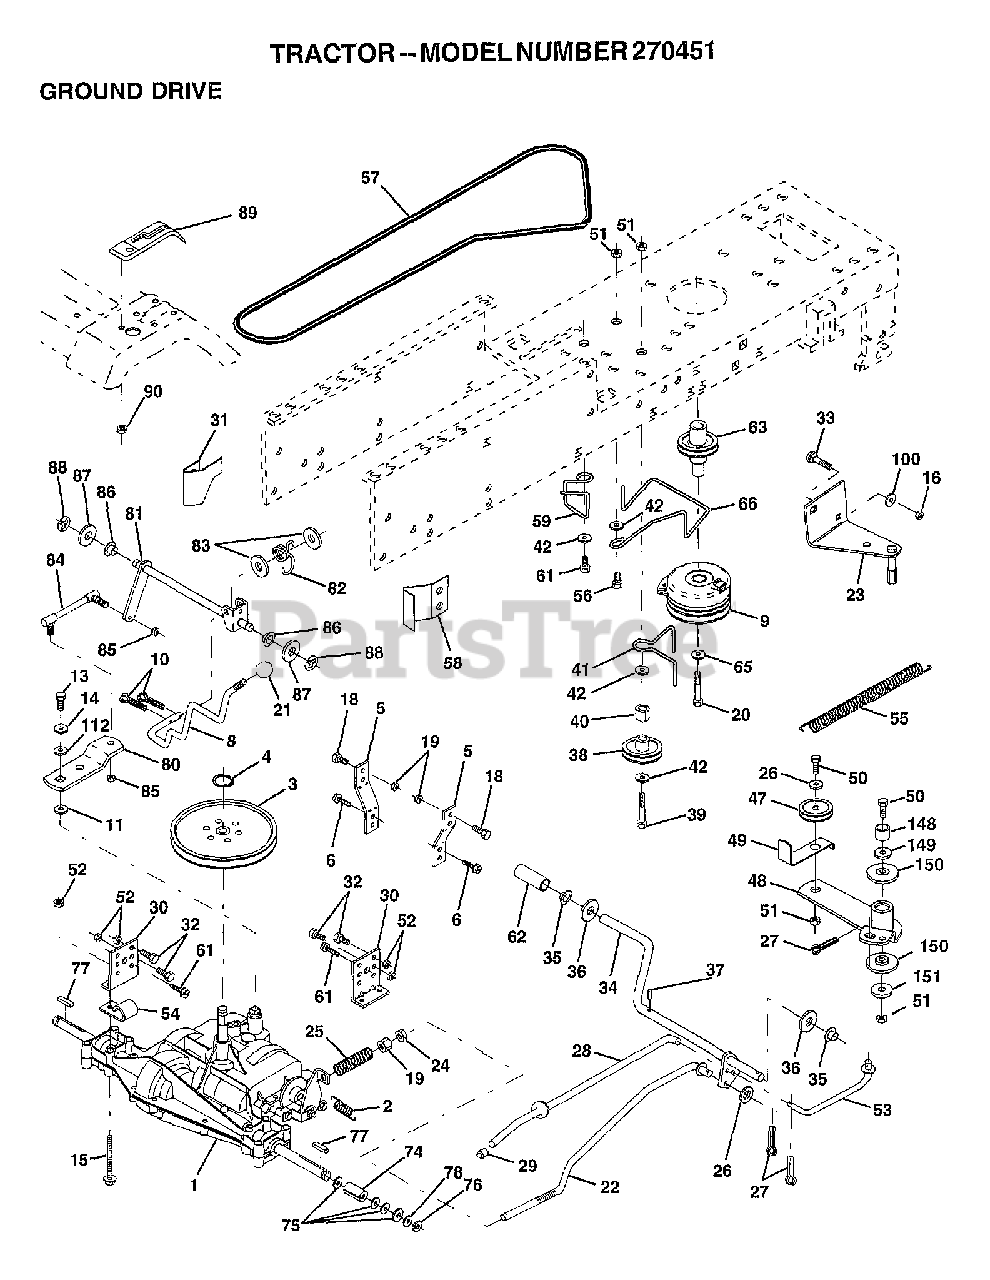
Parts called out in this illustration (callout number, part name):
2	SPRING.BRAKE.RETU
3	PULLEY TRANS
5	STRAP TORQUE
6	SCREW
7	BRKT.SADDLE.SHIFT
8	SHIFT ROD
10	PIN COTTER 1/8
11	WASH-SHFT PLT LT
12	WASHER
13	BOLT.1/4-28.W/PAT
14	LOCKWASHER
15	BOLT.HX.FLG.5/16
18	BOLT
19	NUT
21	KNOB T (1/2-HOLE)
22	BRAKE ROD
24	NUT
25	SPRING ROD LT
26	WASHER
27	COTTER PIN
28	ROD.BRAKE.PARK.LT
29	PLUNGER CAP T
30	TRANSAXLE MTG BKT
32	BOLT
34	SHAFT ASM-PEDAL F
35	NYLON BEARING
36	WASHER LT
38	FLAT IDLER PULLEY
39	BOLT
40	SPACER T
41	"KEEPER,BELT.IDLER FLAT"
42	WASHER
48	BELLCRANK.CLUTCH
49	RETAIN BELT
53	"LINK, CLUTCH T"
55	"SPRING, RETURN LT"
57	"V-BELT,95.3"
59	KEEPER BELT SPAN CTR
61	SCREW
62	PEDAL COVER T
63	PULLEY.ENGINE
64	BOLT
65	LOCKWASHER
66	KEEPER-BELT
70	KEEPER BELT ENG
72	WASHER
74	SPACER LT
75	WASHER
76	E-RING LT
77	SQUARE KEY
78	WASHER
112	WASHER LT
113	"STRAP,TORQUE"
116	BOLT RDHD 3/8-16
150	BUSHING.BELLCRANK.GRD.DR
151	WASHER
170	KEEPER.BELT.TRANSAXLE
202	BOLT.3/8-16X1.50
204	SCREW
